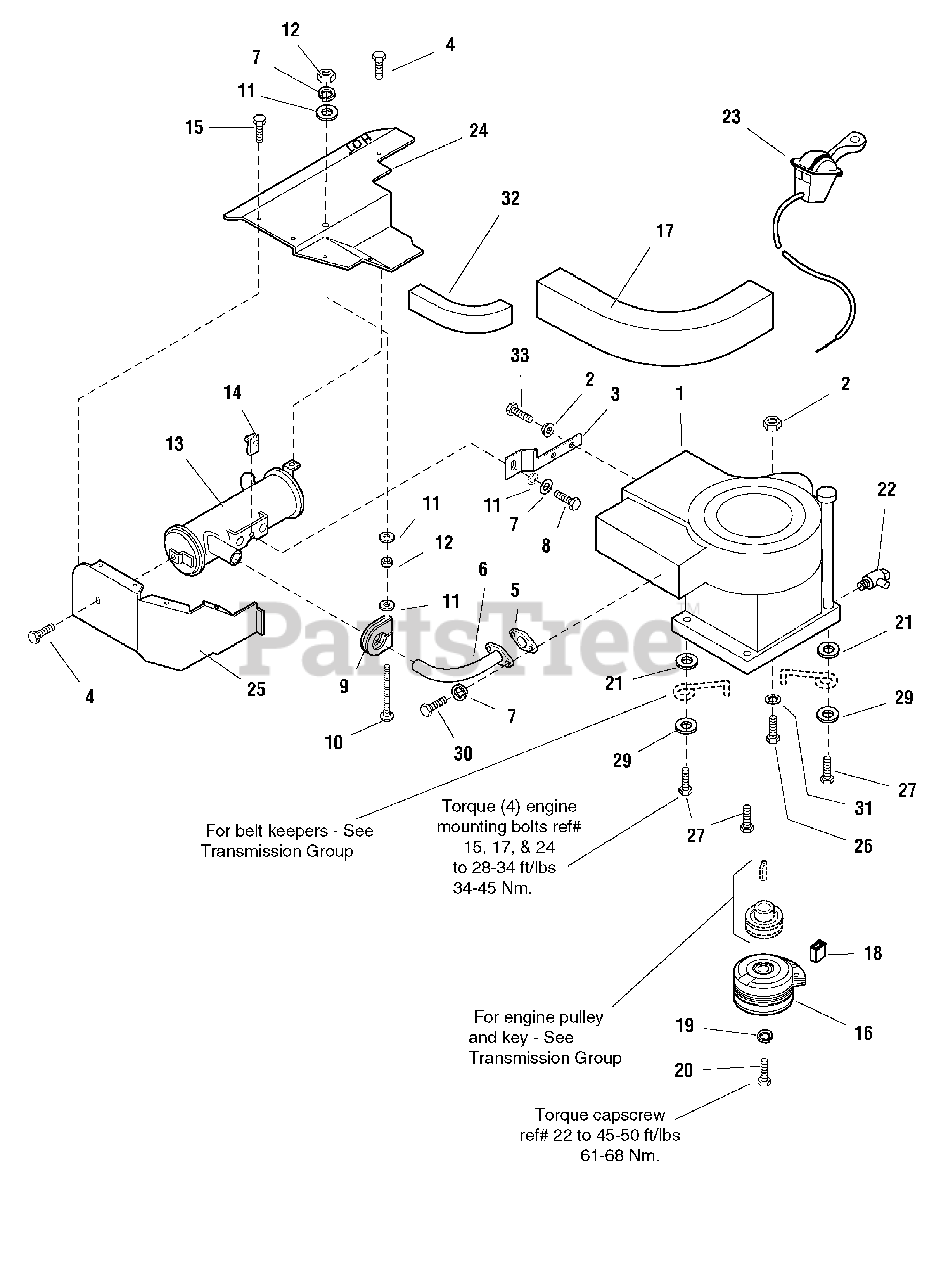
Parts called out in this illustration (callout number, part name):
1	ENGINE, Briggs & Straton, 13.5HP *
2	NUT, Hex Flange, 5/16-18
3	SUPPORT, Muffler
4	CAPSCREW, Taptite, 5/16-18 x 1/2
5	GASKET, Muffler
6	PIPE, Exhaust
7	LOCKWASHER, 5/16
8	CAPSCREW, 5/16-18 x 1
9	CLAMP, Muffler
10	BOLT, Carriage, 5/16-18 x 3-1/4
11	WASHER, 5/16
12	NUT, Hex, 5/16-18
13	MUFFLER ASSEMBLY
14	NUT, Speed, 5/16-18
15	SCREW, #10-16 x 1/2
16	CLUTCH, Electric
17	SEAL, Air Inlet
18	SLEEVE, Clutch Anchor
19	LOCKWASHER, 7/16
20	CAPSCREW, 7/16-20 x 2-12
21	WASHER, Flat, 7/16
22	VALVE, Shut Off
23	THROTTLE CONTROL, Single
24	DUCT, Top, R.H.
25	DUCT, Bottom
26	CAPSCREW, Hex, Whiz, 5/16-18 x 1-1/2
27	CAPSCREW, Taptite, 3/8-16 x 1-1/2
29	WASHER, 3/8
30	CAPSCREW, Socket HEad, 5/16-18 x 3/4
31	PUSHNUT, 5/16
32	EDGING, Seal
33	CAPSCREW, Taptite, 1/4-20 x 7/8
